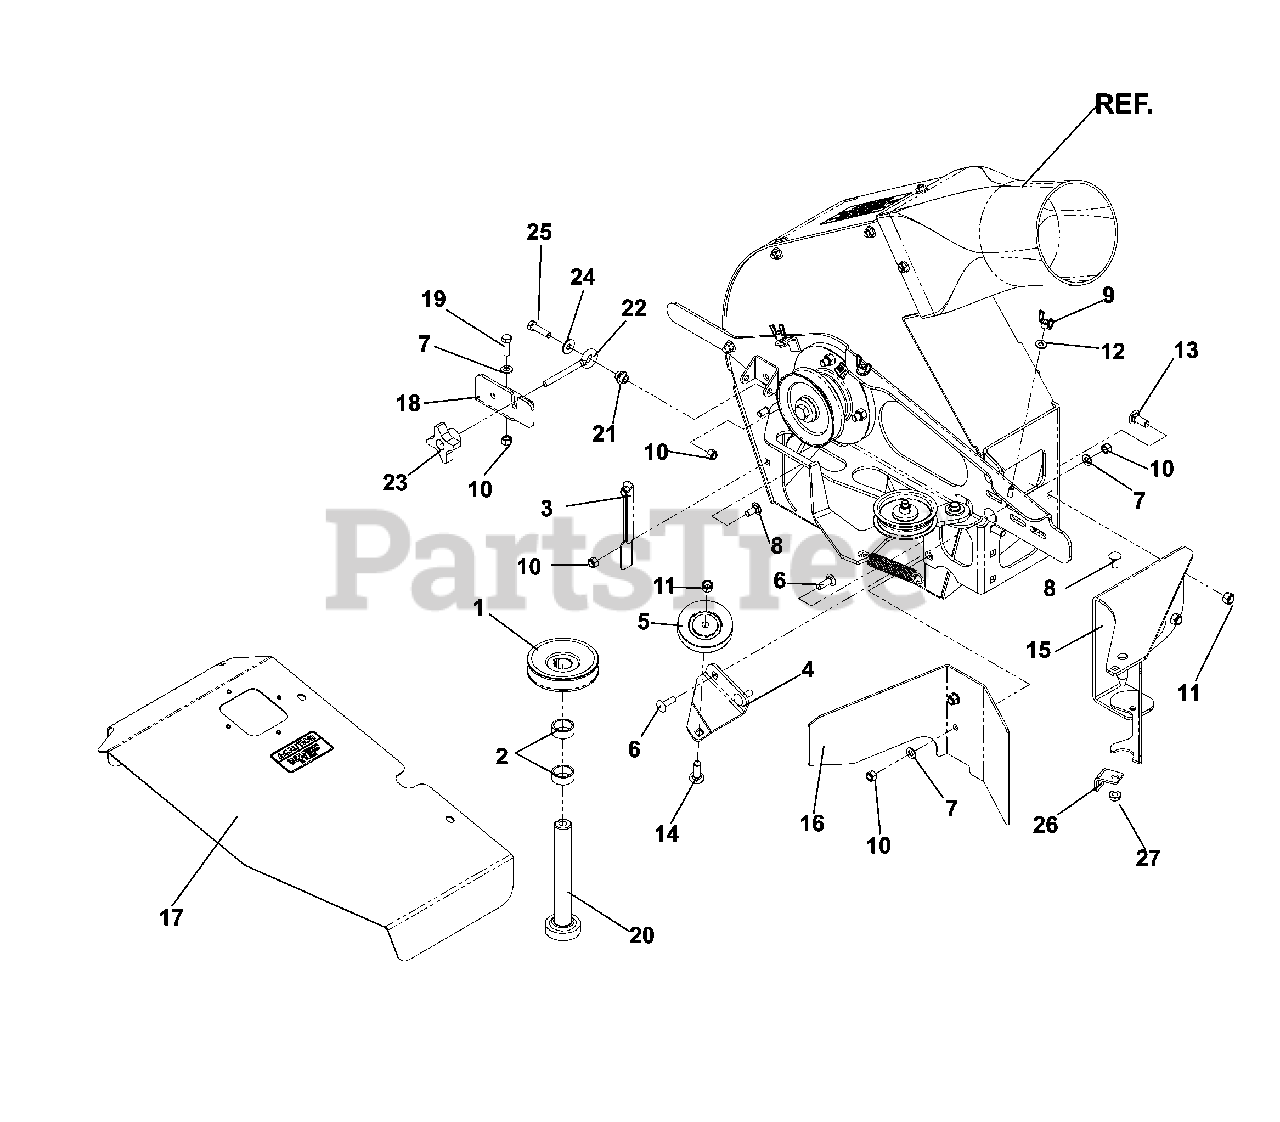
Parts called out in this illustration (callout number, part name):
1	V-PULLEY
2	HUB BEARING SPACER
4	FIXED IDLER BRKT.
5	PULLEY, IDLER 3 METAL
6	RHSSNB 5/16C X 1.0
7	FLAT WASHER 5/16 SAE
8	BOLT 5/16C X 3/4" CARRIAGE
9	WING NUT 1/4
10	NUT 5/16 NYLOC
11	NUT 3/8-16 NYLOC
12	1/4` SAE FLAT WASHER
13	RHSNB 3/8C X 1
14	RHSNB, 3/8-16 X 1-1/2
15	PIVOT WLDT.
16	BLOCK OFF PLT
17	GUARD ASSEMBLY, 60"
18	LATCH RECEIVER
19	HCS 5/16C X 1
20	SHAFT LONG
21	SPRING CAP
22	EYE BOLT 5/16 X 3.50
23	SEAT KNOB 5/16-18
24	WASHER 5/16 FLAT
25	HCS 5/16C X 1 1/4
26	SPRING BRKT.
27	5/16-18 FLANGED L-NUT
